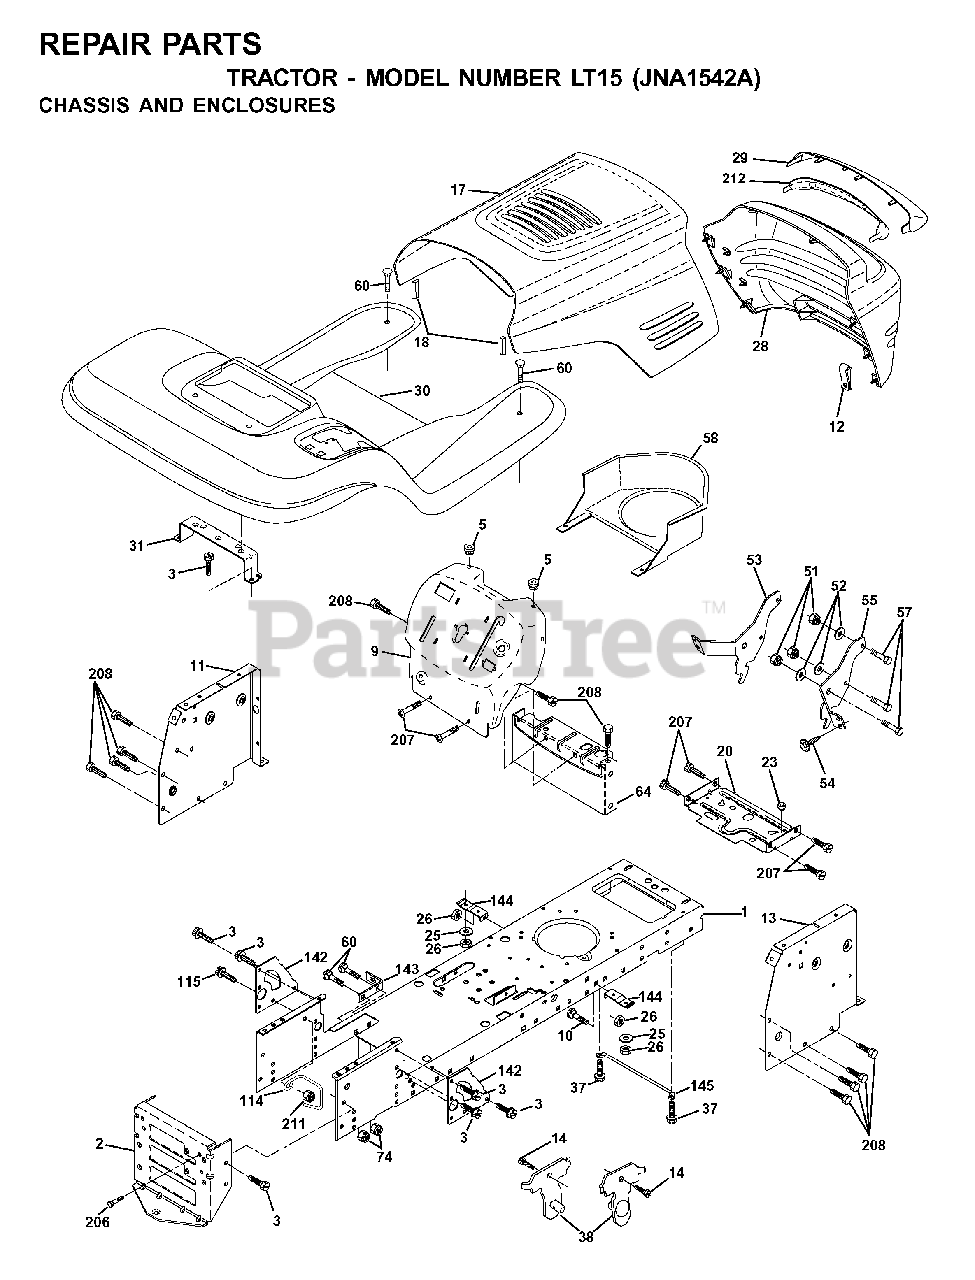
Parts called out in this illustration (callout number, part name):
1	CHASSIS STAMPING
2	DRAWBAR, 12GA
3	SCREW 3/8-16X3/4
5	BUMPER.RUBBER.HOOD
10	BOLT D
11	PANEL DASH LH
13	DASH PANEL RH
14	SCREW LT
18	BUMPER HOOD T
20	PLATE MTG
23	GROMMET T
25	WASHER
26	NUT
37	SCREW LT
38	BRACKET.ASM.PIVOT.MOWER.REAR
51	LOCKNUT
52	WASHER
53	BRACKET.GRILLE.LH
57	BOLT
58	AIR DUCT P/L/LT
64	DASH LOWER
74	LOCKNUT
115	SCREW.3/8-16
142	PLATE
143	BRACKET, SWAY BAR
144	BRACKET FOOTREST
145	ROD PIVOT CHASSIS/HOOD
206	SHOULDER BOLT 5/16-18TT
207	SCREW, 5/16-18 X 1/2
208	SCREW 3/8-16X1/2
211	NUT
